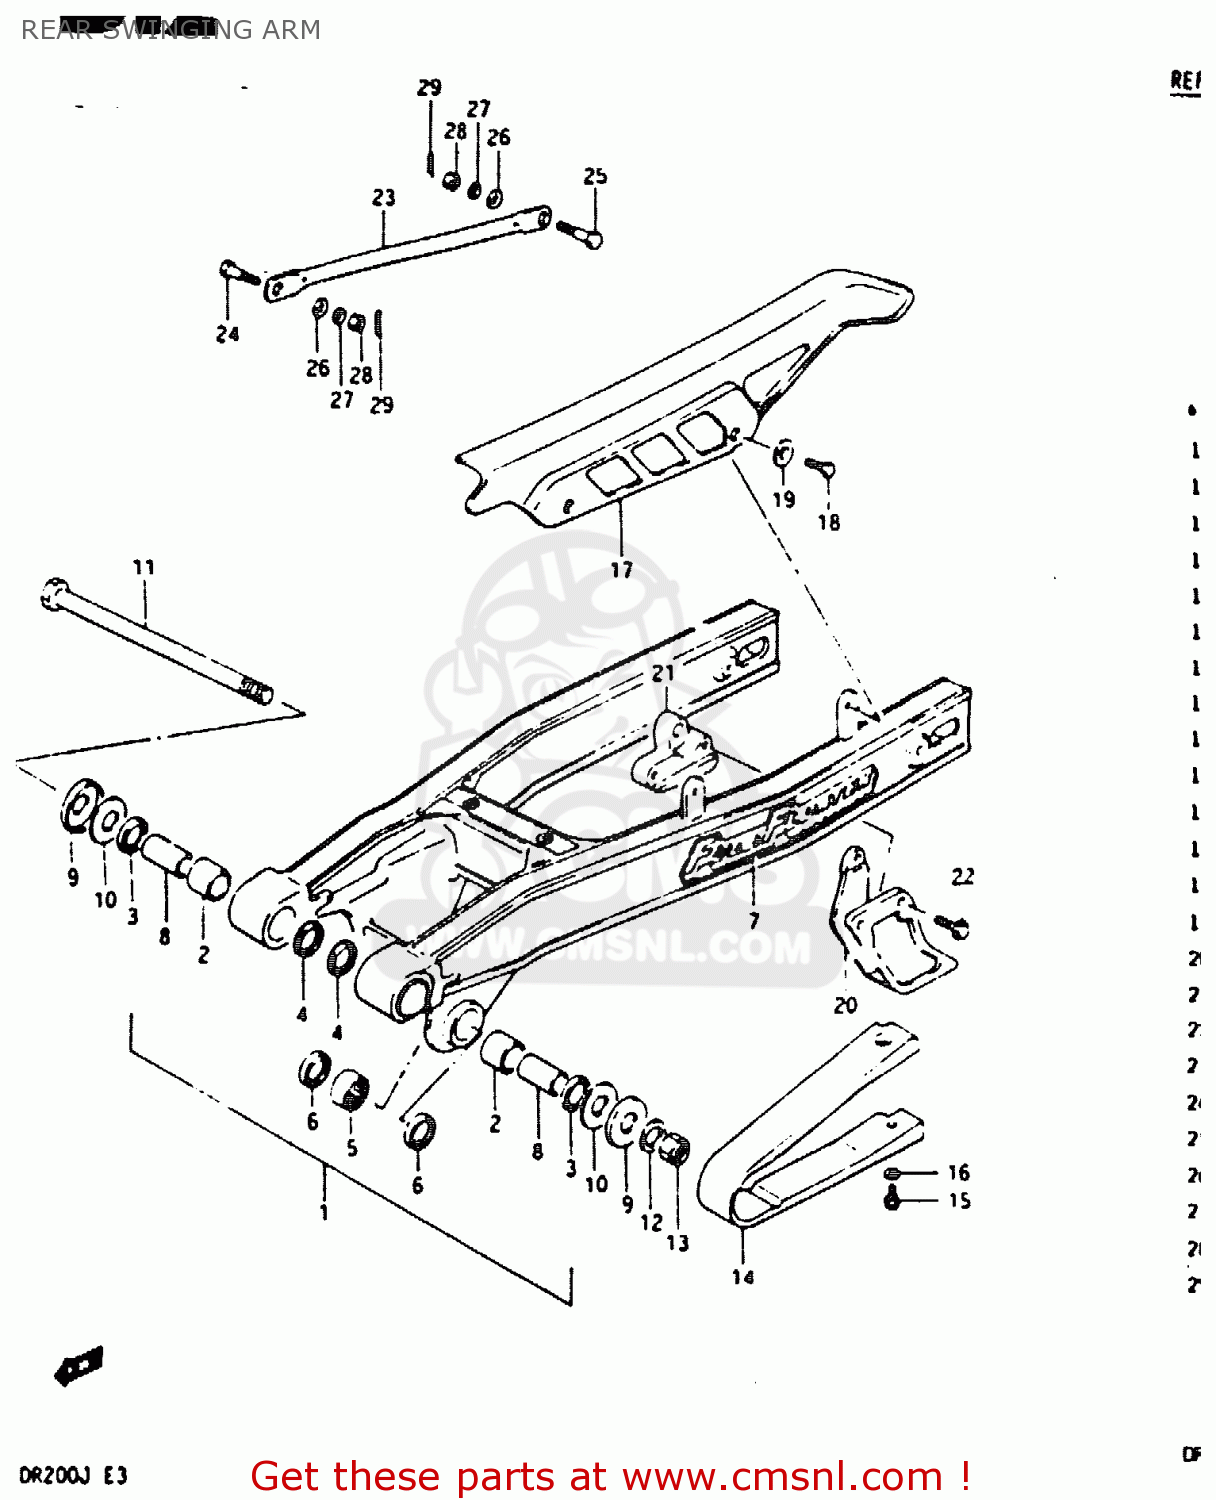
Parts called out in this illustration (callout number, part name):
1	SWING ARM ASSEMBLY,REAR
2	BUSHING,RR SWGARM PIVOT
3	OIL SEAL
4	SEAL,OIL(20X27X5)
5	BEARING
6	SEAL,CUSHION LEVER OUT DUST
7	EMBLEM
8	SPACER,RR SWGARM PVT
9	COVER,RR SWGARM DUST SEAL
10	WASHER
11	SHAFT,REAR SWING ARM
12	WASHER
13	NUT
14	BUFFER,CHAIN TOUCH DEFLECTOR
15	BOLT
16	WASHER
17	CASE,CHAIN
18	BOLT
19	WASHER
20	GUIDE,CHAIN
21	RUBBER,CHAIN GUIDE
22	BOLT
23	TORQUELINK,RR
24	BOLT,TORQUE LINK,FRONT
25	BOLT(8X26.5)
26	WASHER
27	LOCK WASHER
28	NUT
29	PIN 20X20
